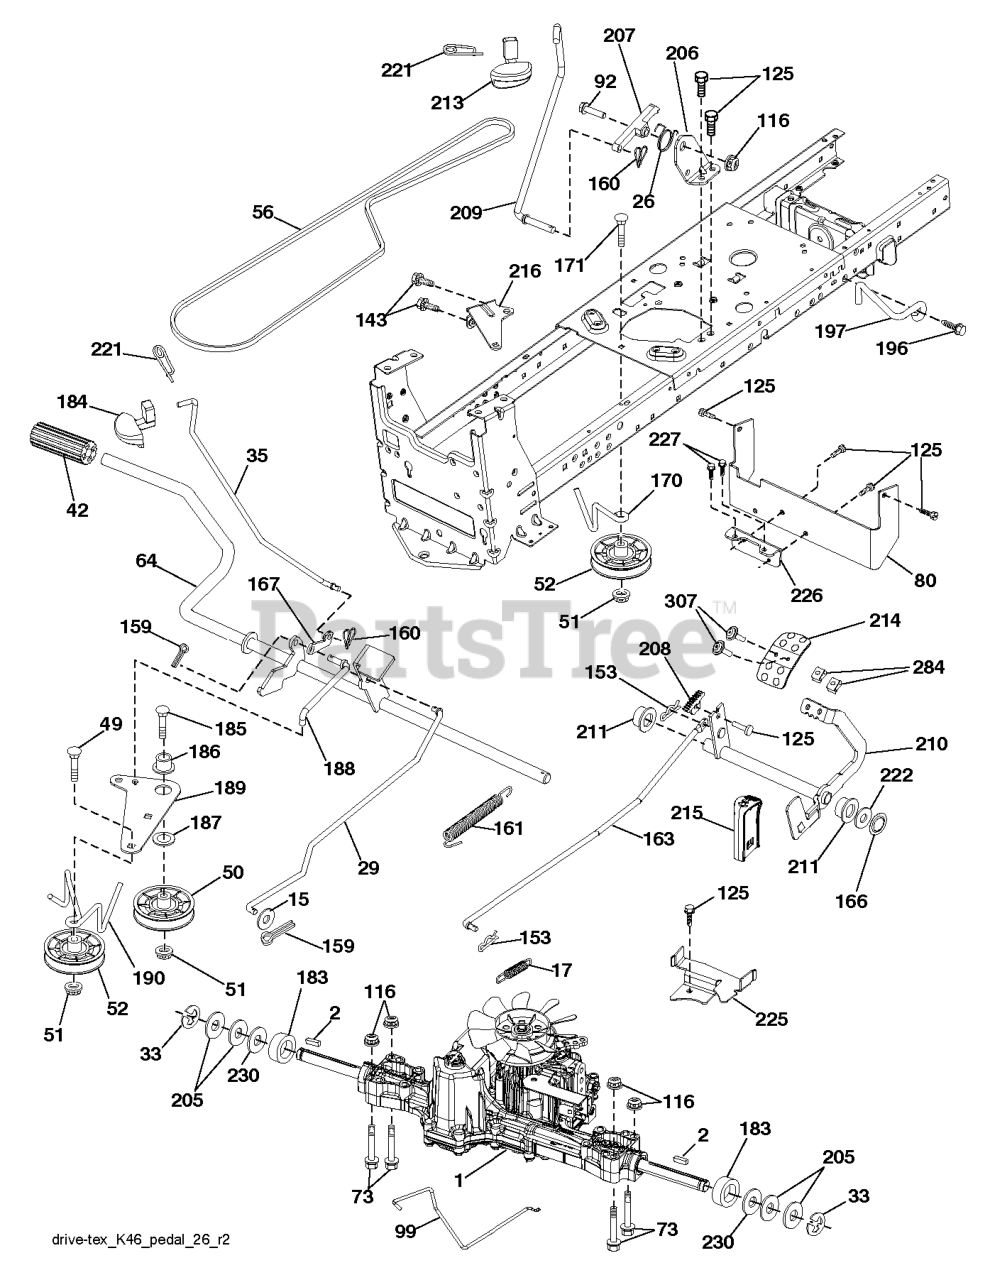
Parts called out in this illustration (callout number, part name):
2	SQUARE KEY
15	WASHER
17	SPRING.BRAKE.K46.GREEN
26	SPRING.RETURN.CRUISE
29	ROD.BRAKE.K46
35	ROD .BRAKE. PARKING. GT. HUSQ.
42	PEDAL COVER T
50	IDLER.FLAT.910.OFFSET
51	NUT LOCK FLG 3/8-16 UNC
52	IDLER.V-GROOVE.910.OFFSET
56	V-BELT.MOWER.92.40.42/K46
64	SHAFT.ASM.PEDAL.BRK.CNTR
80	STRAP TORQUE
92	BOLT
99	ROD.SPRING.BYPASS.K46.LT.Z
116	NUT LOCK HEX FLANGE 5/16-18
125	SCREW
143	Screw 5/16-18 x 1/2 Hex, Self Tapping 5/16-18 x 1/2
153	RETAINER M
159	COTTER PIN
160	RETAINER CLIP
161	SPRING, RETURN LT
163	ROD.CONTROL.K57R.K46
166	NUT.PUSH.625
167	LATCH.BRAKE.SPRING
170	KEEPER.V-IDLER.CENTER.
183	SPACER AXLE
184	HANDLE.PARKG.BRK.HUSQ X667
186	SPACER.RETAINER
187	WASHER 12/32X2X10GA
188	RP.LINK.CLUTCH.GROUND.DRIVE
189	BELLCRANK.GROUND.DRIVE.TEX.
190	KEEPER.BELLCRANK.DRIVE
196	SCREW 3/8-16X1
197	LINK.CLUTCH.ANIT-ROTAT
206	BRKT.MOUNT.LATCH.CRUIS
207	LATCH.CONTROL.CRUISE
208	GEAR.SECTOR.CONTROL.CR
209	ROD.CONTROL.CRUISE.GT.
210	ROCKER.ASM.PEDAL.CONTR
211	BEARING.NYLON
213	KNOB.CONTROL.CRUSIE.HU
214	PEDAL.FORWARD.HUSQVARNA.DEALER
215	PEDAL.REVERSE.TEX.GT.4
216	BRACKET.PULLEY.IDLER.W/TEX
221	RETAINER.SPRING.CLIP.H
222	WASHER 21/32 X 1-1/4 X 10 GA.
225	KEEPER.BELT.TRANSAXLE.K46
226	BRACKET.MOUNT.TORQUE.K46.TLT
227	SCREW.THDROL.5/16-18X3/4.TTY
230	WASHER.HARDENED
284	NUT.U-CHNL.1/4-20.550DP.350PNL
307	SCREW.MACHINE.CR.1/4-20
